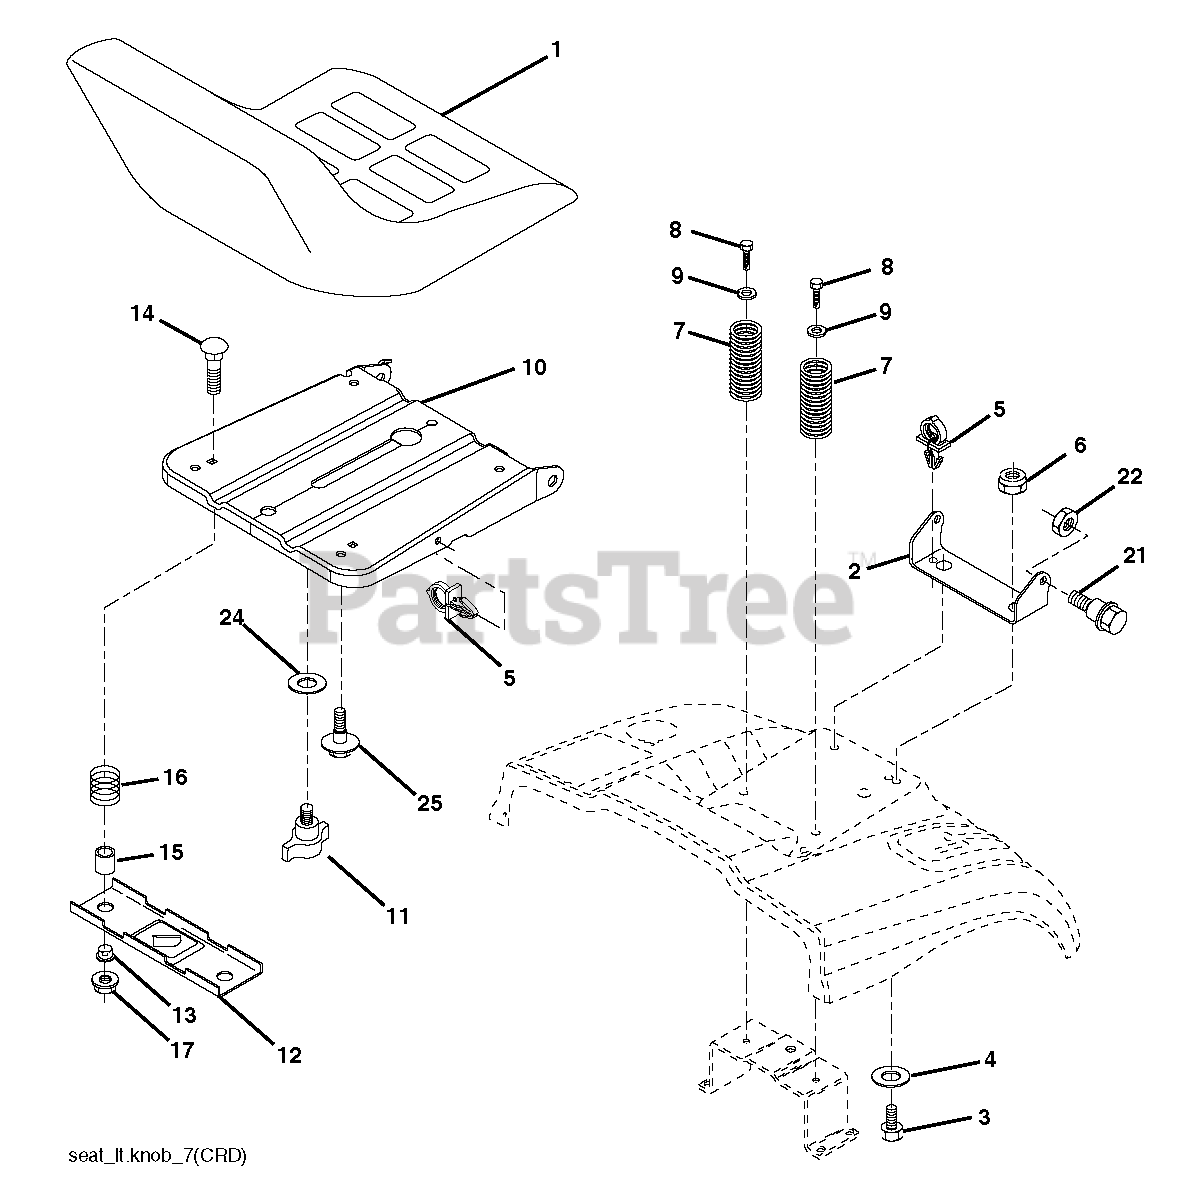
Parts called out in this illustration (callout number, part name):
1	SEAT.XG150.BLK.KB/SLD.NO-LOGO
2	SEAT PIVOT BRKT
4	WASHER PM
5	PUSH CLIP
6	NUT
7	SPRING COMPRESSION
8	SCREW 3/8-16X1
9	WASHER
10	PAN.ASM.SEAT.1SLOT
11	KNOB.SEAT.ADJ.WINGNUT
12	BRKT.MNTNG.SWITCH.SEAT
14	BOLT.ROUND.HEAD.SQUARE.NECK
15	SPACER SPLIT
16	SPRING COMPRESSED
17	NUT T
21	BOLT.SHOULDER.5/16-18
22	NUT.71038.31-18.HEX.NYLOCK
25	BOLT,SHOULD
